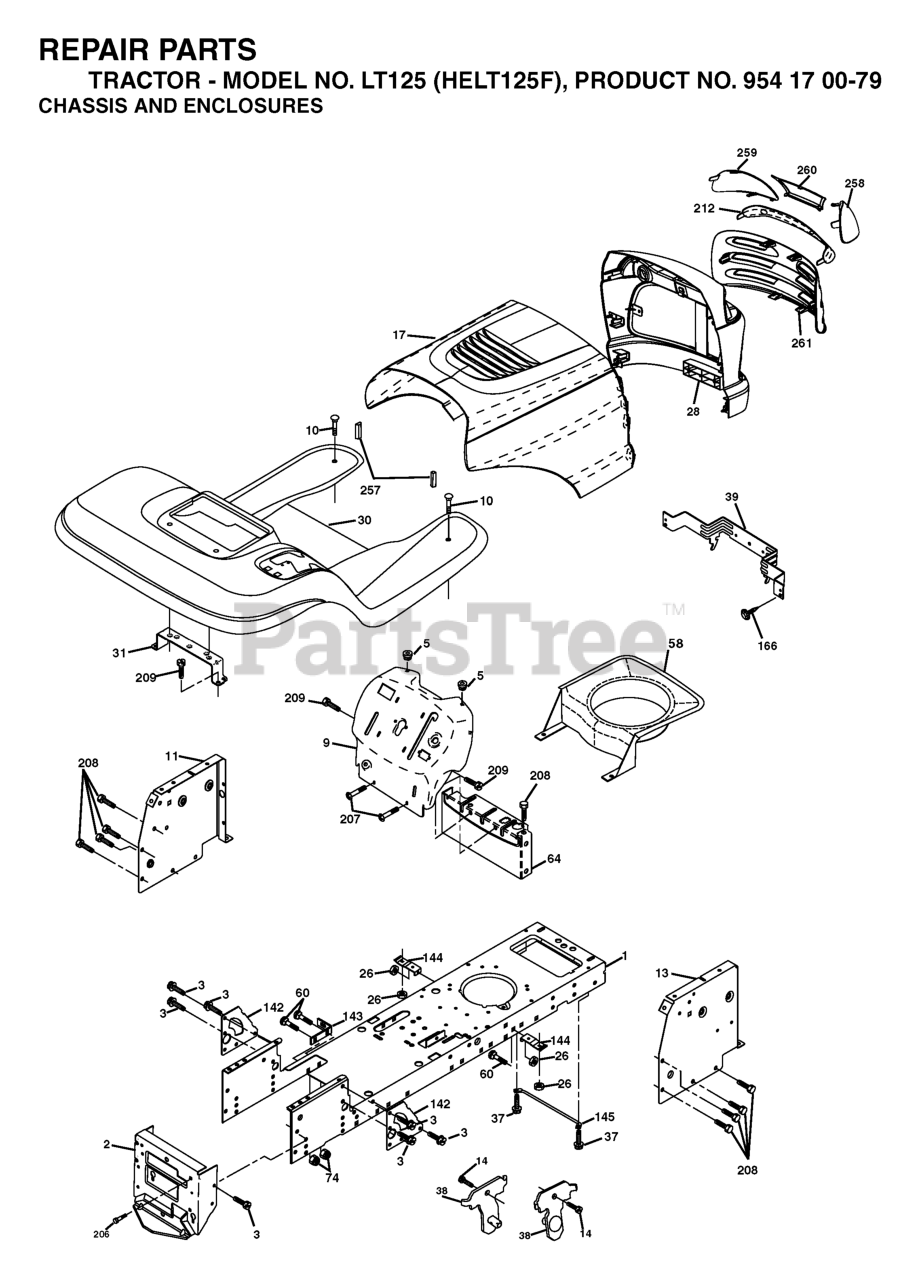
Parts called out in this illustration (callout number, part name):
1	CHASSIS STAMPING
2	DRAWBAR, 12GA
3	SCREW 3/8-16X3/4
5	BUMPER.RUBBER.HOOD
9	DASH
10	BOLT D
11	PANEL.DASH.LH.LTX
13	PANEL DASH RH
17	HOOD
26	NUT
30	FENDER FOOTREST
31	BRACKET.SUPPORT.FENDER
37	Screw 5/16-18 x 1/2 Hex, Self Tapping 5/16-18 x 1/2
38	BRACKET.ASM.PIVOT.MOWER.REAR
39	BRACKET PIVOT LASER
58	AIR DUCT P/L/LT
60	Bolt - Rd. Hd. Sq. Neckiage 3/8 16 x 3/4
64	DASH LOWER
142	PLATE REINFORCEMENT
143	BRACKET, SWAY BAR
144	BRKT, FOOT REST
145	ROD PIVOT CHASSIS/HOOD
166	SCREW
206	SHOULDER BOLT 5/16-18TT
207	SCREW, 5/16-18 X 1/2
208	SCREW 3/8-16X1/2
209	SCREW, 3/8-16X3/4
212	INSERT.LENS.REFLECTIVE
257	BUMPER.HOOD.LARGE.1.75"
258	LENS LH
259	LENS LH
260	COVER.LENS.HUSQ.LASER
